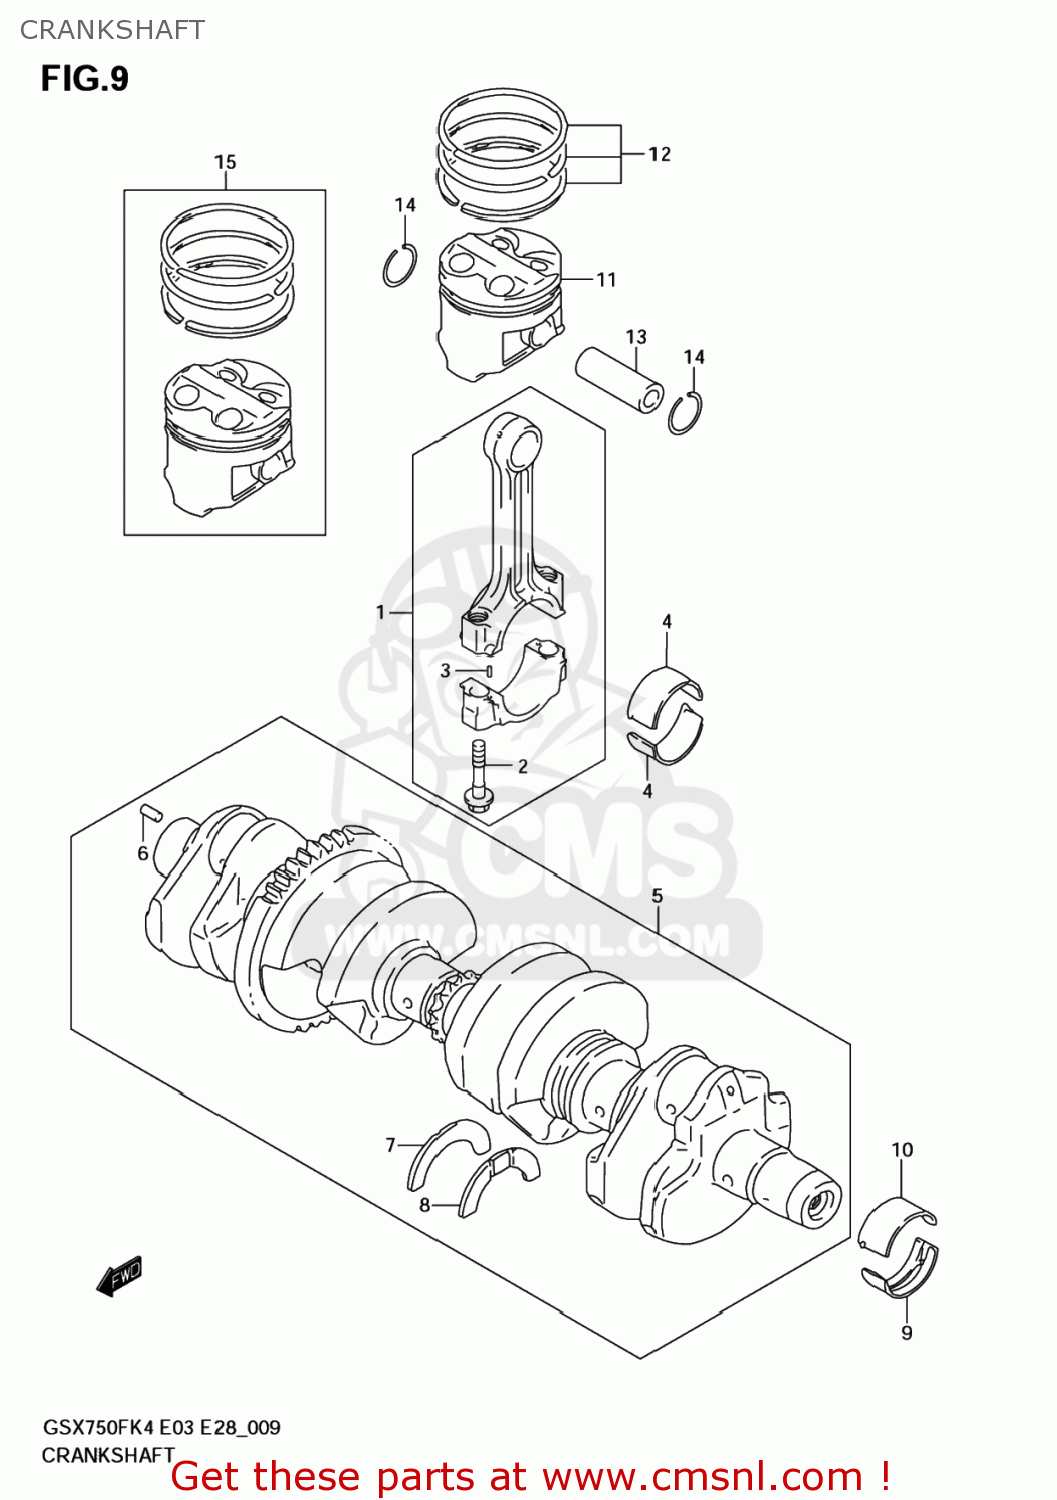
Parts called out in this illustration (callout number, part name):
1	CONNECTING ROD ASSY
2	BOLT,CONNECTING ROD
3	PIN,CONNECTING ROD
4	BEARING,CRANK PIN
5	CRANKSHAFT SET
6	PIN
7	PLATE,CRANK THRUST
8	PLATE,CRANK THRUST
9	BEARING,CRANKSHAFT LWR
10	BEARING,CRANKSHAFT UPR
11	PISTON
12	RING SET,PISTON
13	PIN,PISTON
14	CIRCLIP
15	PISTON SET(OS:0.5)
